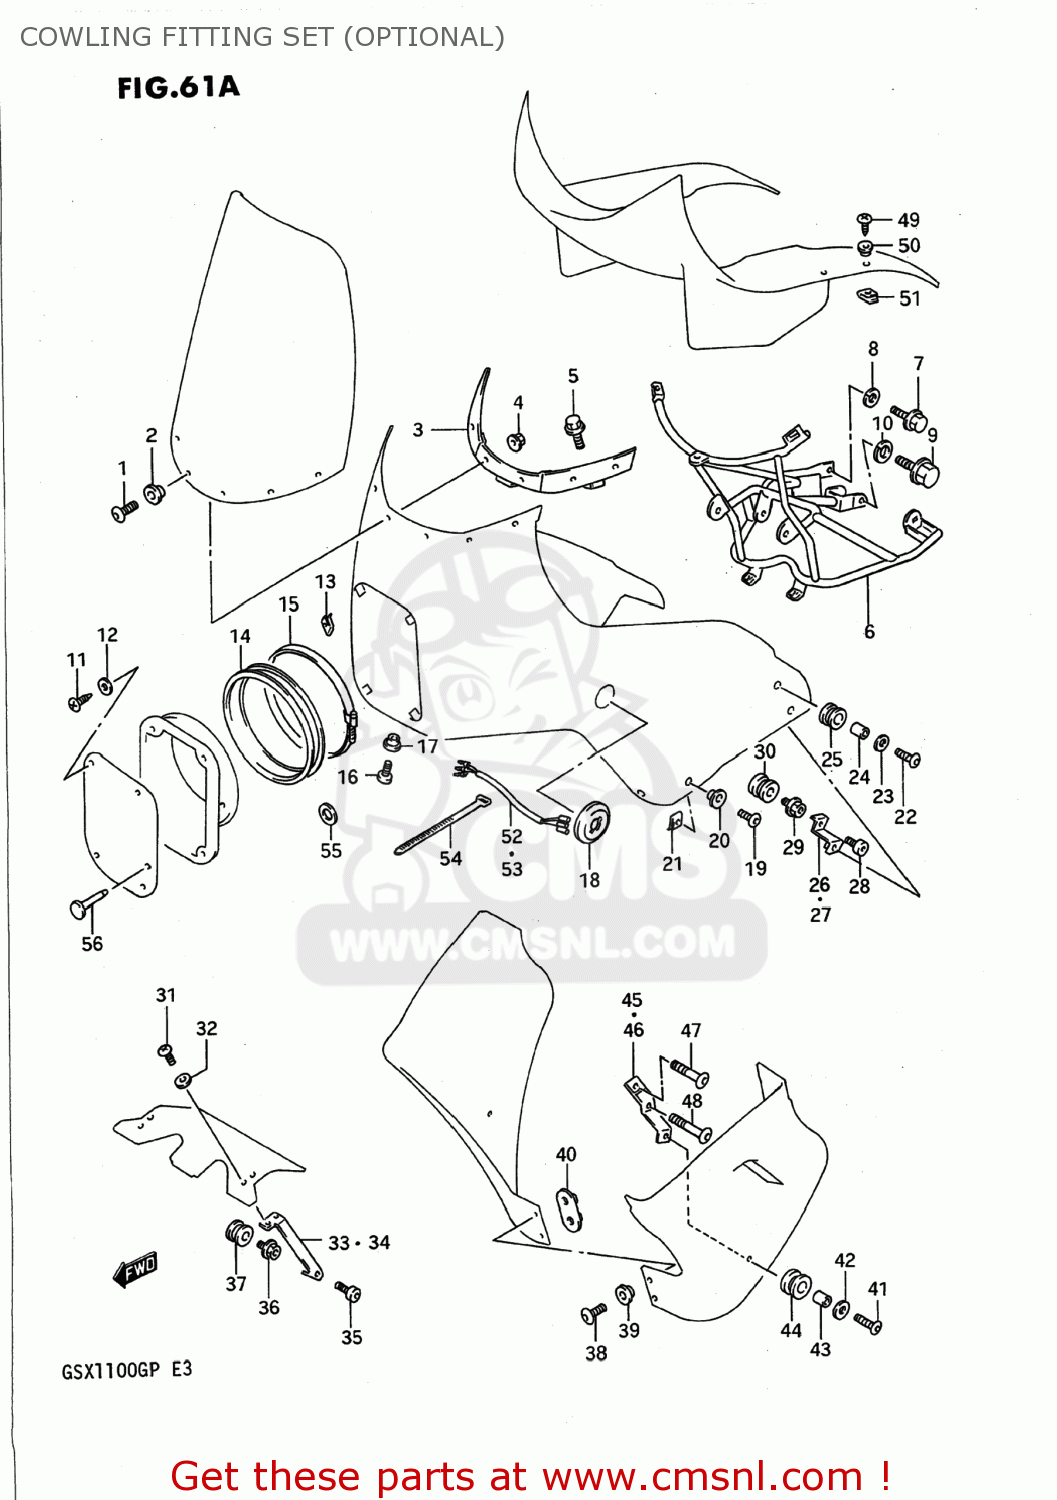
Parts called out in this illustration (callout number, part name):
1	SCREW(6X25)
2	WASHER(6.3X16X1.5)
3	BRACE ASSEMBLY,COWLING,UPPER
4	NUT
5	BOLT, LOWER
6	BRACE,COWLING
7	BOLT, LOWER
8	WASHER,LOCK,8.
9	BOLT
10	WASHER,LOCK
11	SCREW
12	WASHER(5.2X11X1)
13	NUT
14	SHADE,HEADLAMP
15	CLAMP,HEADLAMP
16	SCREW(6X16)
17	WASHER(6.3X16X1.5)
18	GROMMET
19	SCREW(5X18)
20	WASHER(5.2X14X1.5)
21	NUT,HEADLAMP HOUSING,UPPER
22	SCREW(6X20)
23	WASHER(6.5X18X1)
24	SPACER (6.1X9X10)
25	CUSHION
26	BRACE,COWLING,REAR,RIGHT
27	BRACE,COWLING,REAR,LEFT
28	BOLT
29	PLUG
30	GASKET(14X19.2X2) (NAS)
31	SCREW, FRONT & REAR
32	WASHER(5.2X11X1)
33	PLATE,HEAT GUARD,RIGHT
34	PLATE,HEAT GUARD,LEFT
35	BOLT
36	PLUG
37	GASKET(14X19.2X2) (NAS)
38	SCREW(6X16)
39	WASHER(6.3X16X1.5)
40	BRACE,COWLING LWR COVER RR
41	SCREW(6X20)
42	WASHER(6.5X18X1)
43	SPACER (6.1X9X10)
44	CUSHION
45	BRACE,COWLING,LOWER,RIGHT
46	BRACE,COWLING,LOWER,LEFT
47	BOLT, LOWER
48	BOLT
49	SCREW
50	WASHER(5.2X14X1.5)
51	NUT
52	WIRE
53	WIRE,FRONT TURN LEAD,LEFT
54	CLAMP(L:125)
55	WASHER
56	PLUG,HEADLAMP
